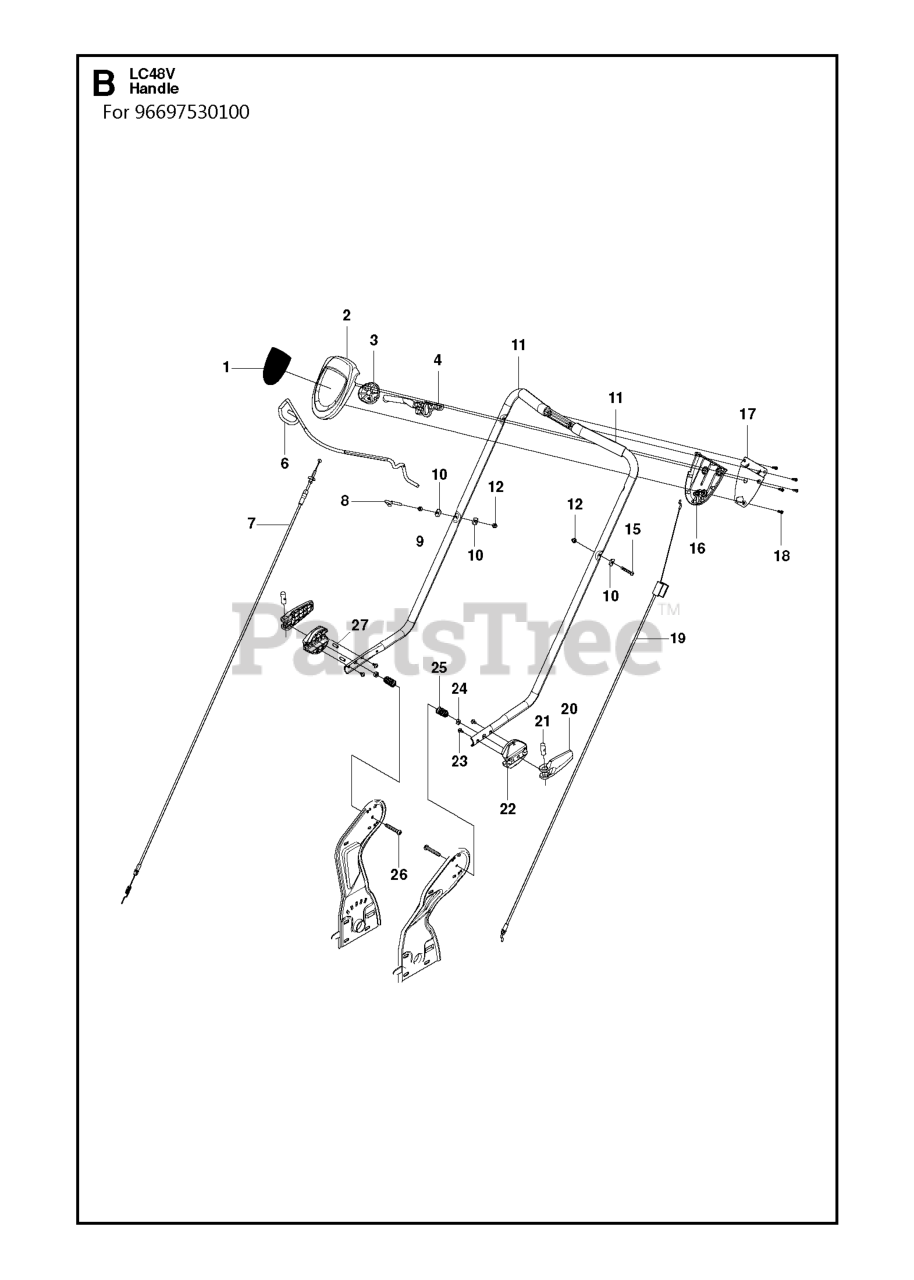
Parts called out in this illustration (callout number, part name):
2	COVER, DRIVE CONTROL BOTTOM
3	PULLEY.CAM.DRIVE.CONTROL.EZ
4	LEVER, DRIVE CONTROL
16	COVER, DRIVE CONTROL, TOP
17	BRACKET, DRIVE CONTROL
18	SCREW ITXPANT T50X16 ZN/FE (A
23	SCREW ITXPANTT M5X10 ZPB (A00
